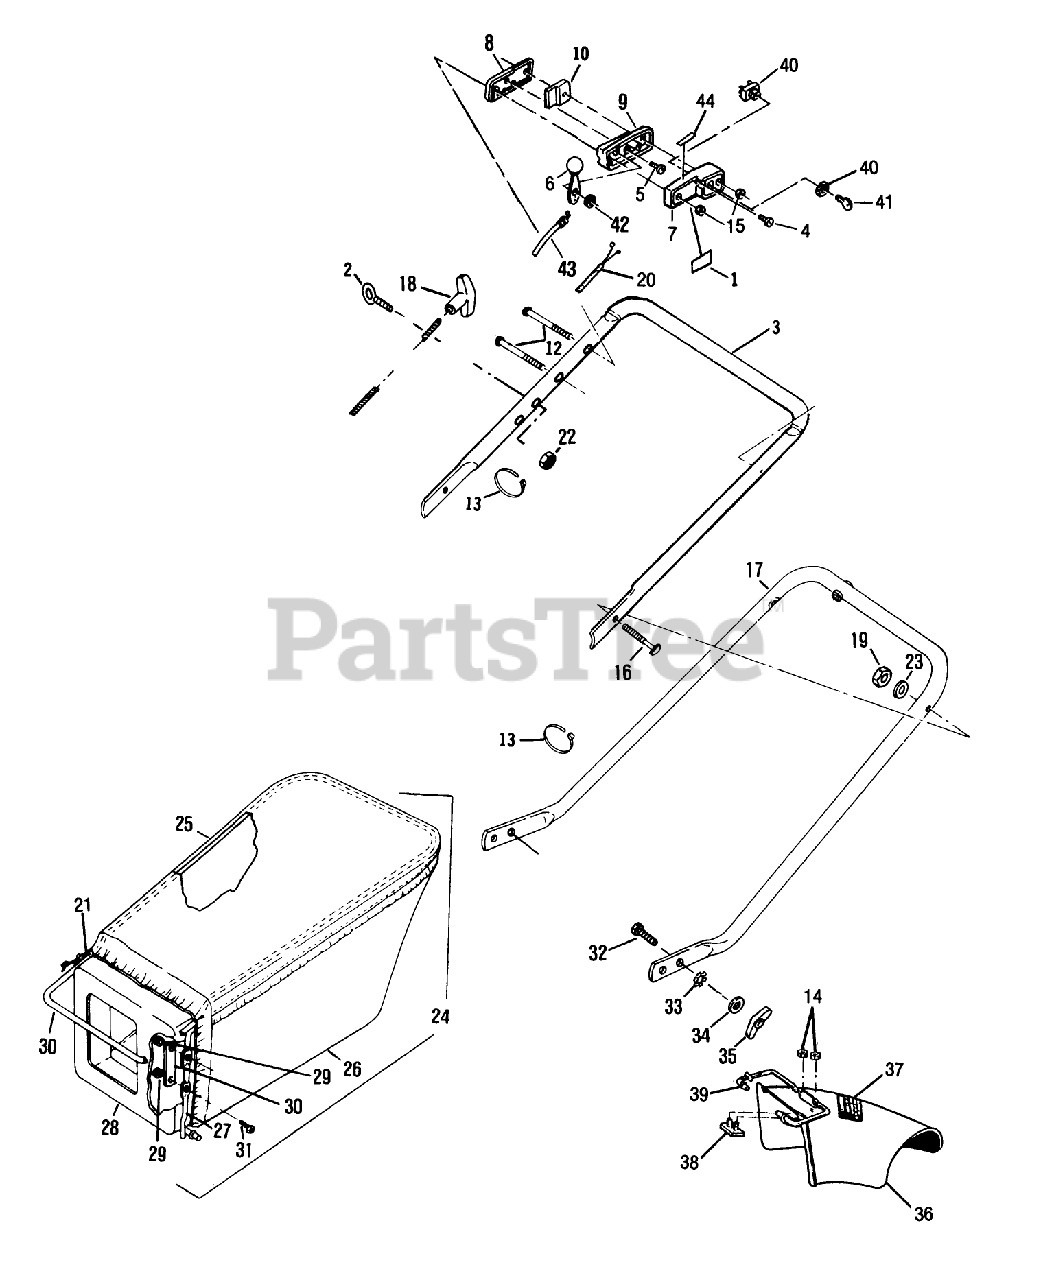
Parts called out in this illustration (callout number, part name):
2	EYE BOLT WAS MFG
4	SCREW
6	LEVER&KNOB AY WES
7	CASE THROTTLE
8	OUTER CONTROL CASE
11	SCREW
14	Nut
15	NUT C/LOCK E
17	HANDLE SECTION
18	HANDLE START UM&D
19	NUT-LOCK F
22	LOCKNUT E
23	WASHER-CURVED
25	HANGER BAG TROX
28	BAG ADAPTOR PL
29	LOCKNUT E
34	WASHER
35	NUT-WING
39	LATCH BAR ARGO
40	SWITCH AY
42	WASHER-SPRING
43	T/CABLE WESCON
